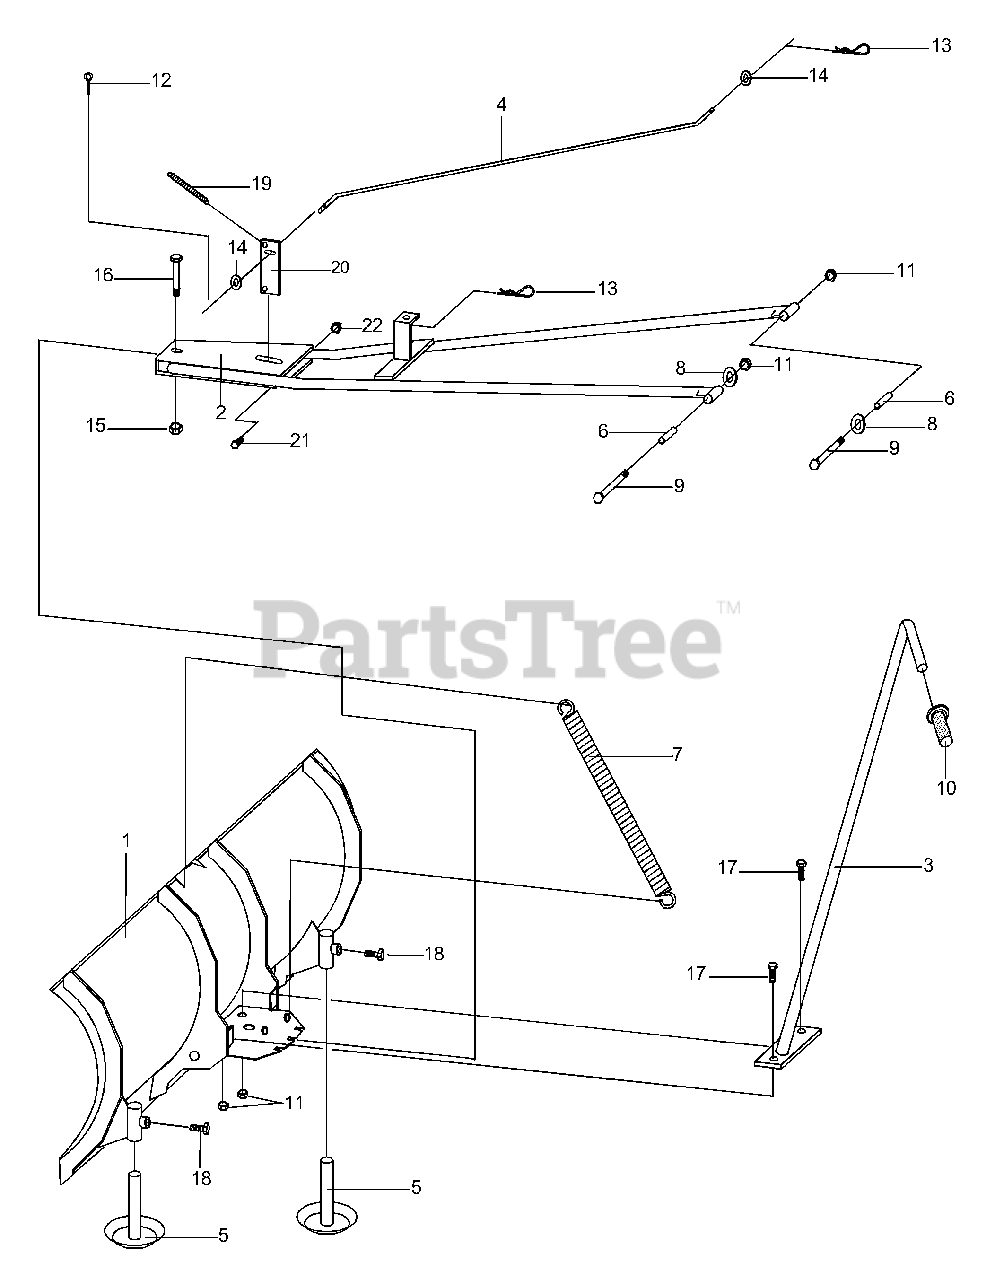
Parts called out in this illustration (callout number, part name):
3	Angle Control Tube
4	Angel control Rod
12	Pin, Split
13	Pin, Spring
20	Plate, Lock
